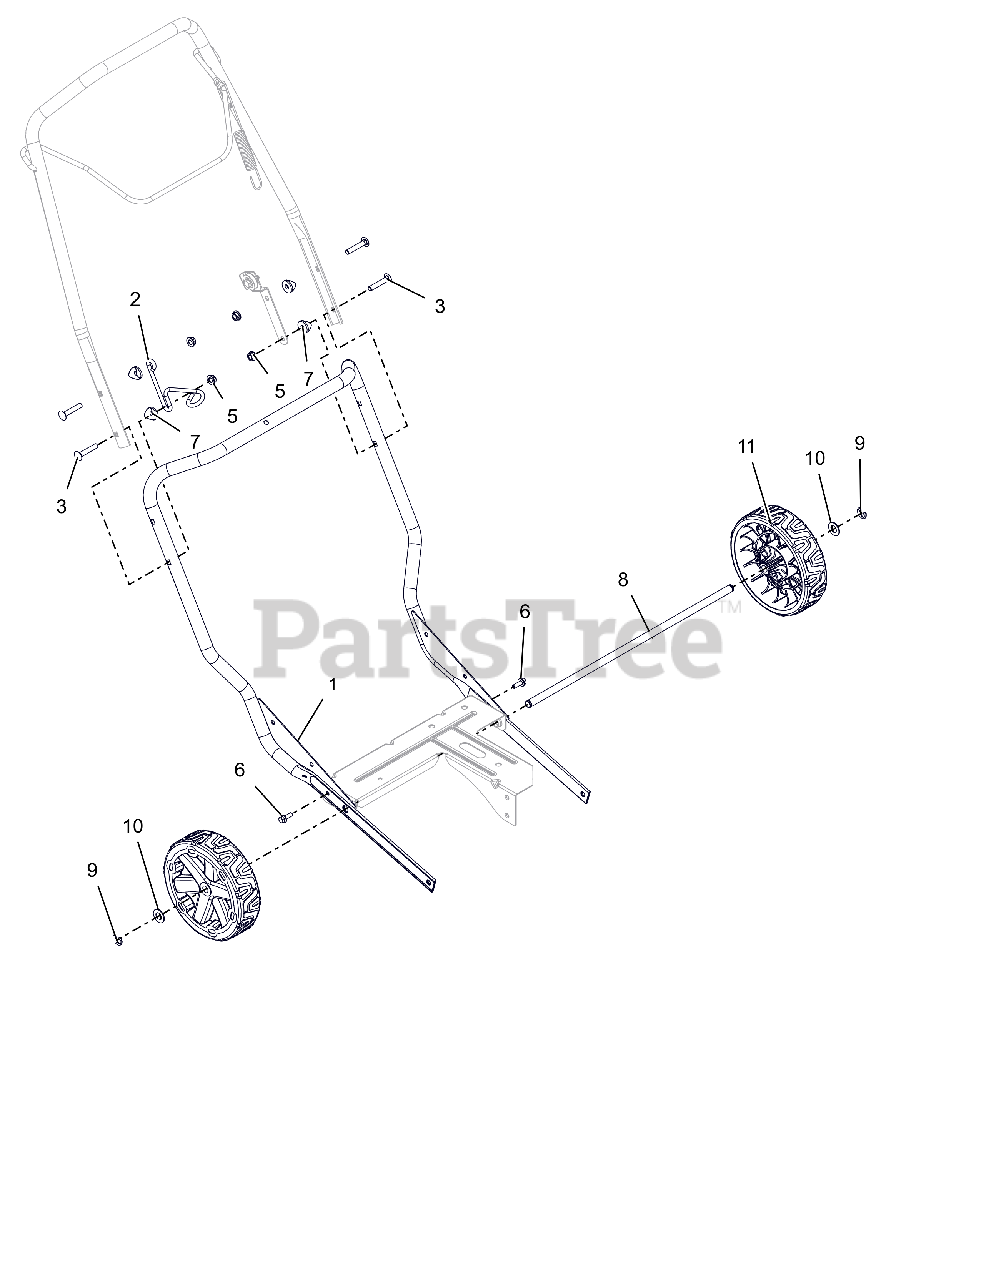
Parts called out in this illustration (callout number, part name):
1	HANDLEBAR, LOWER - W/DECAL
2	HOLDER, RECOIL
3	@BLT-RDHDSQNK .31-18X1.75 G5YZ
5	@NUT-LK-CTR-FLG .31-18 YZ GR F
6	BLT,HEX-FLG .25-20X.75 G5 ZCC
7	SPACER, HANDLEBAR
8	SHAFT, AXLE
9	RG-RTNG-EXT .500X.042 (E)
10	WSHR-FL-STL.531X1.00X.063 YWZC
11	TIRE/WHEEL- 7.5 X 2.0
